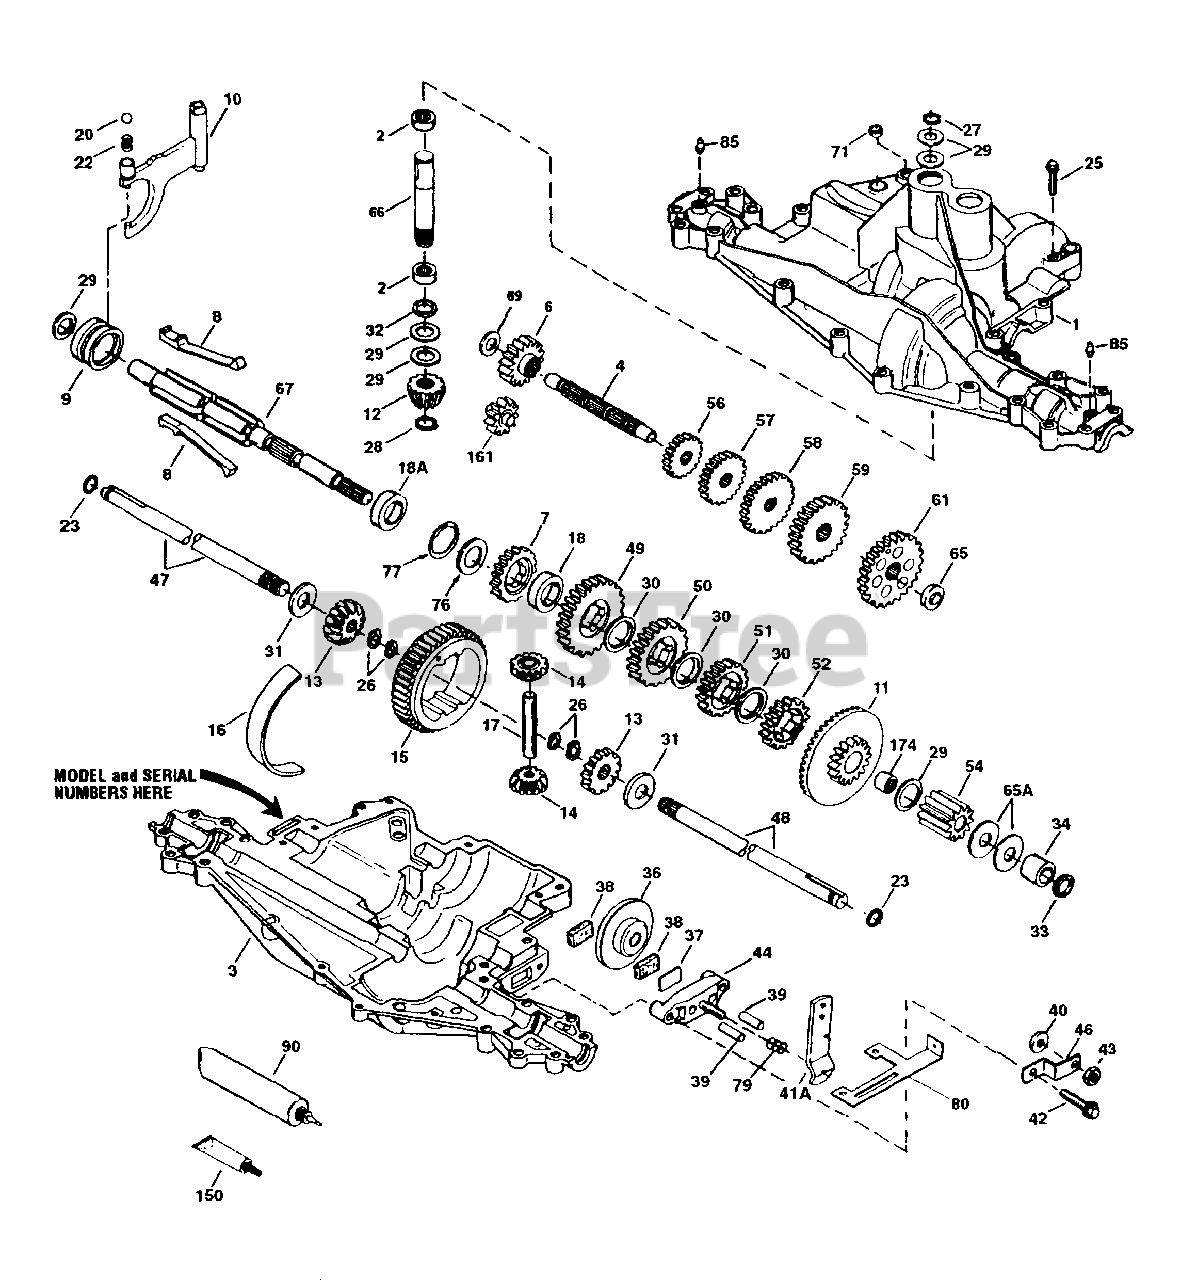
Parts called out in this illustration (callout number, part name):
1	Transaxle Cover
2	Needle Bearing
3	Transaxle Case
6	Spur Gear (16 teeth)
7	Spur Gear (22 teeth)
8	Shift Key
9	Shift Collar
10	Shift Rod 8 Fork
11	Bevel Gear & Bearing
12	Bevel Pinion (14 teeth)
13	Bevel Gear (16 teeth)
14	Differential Pinion
16	Bearing Strip
18	Neutral Spacer
18A	Neutral Spacer
20	Ball, 5/16" dia
25	Screw, 1/4-20 x 1-1/4"
26	Retaining Ring
27	Retaining Ring
28	Retaining Ring
37	Brake Pad Plate
38	Brake Pad (pkg. of 2)
40	Washer
42	Screw, 1/4-20 x 1-1/4"
43	Locknut, 5/16-24
44	Brake Pad Holder
46	Brake Lever Bracket
47	Axle (16-1/4" long)
48	Axle (11" long)
49	Spur Gear (30 teeth)
50	Spur Gear (25 teeth)
51	Spur Gear (22 teeth)
52	Spur Gear (19 teeth)
54	Spur Gear (11 teeth)
56	Spur Gear (20 teeth)
57	Spur Gear (25 teeth)
58	Spur Gear (28 teeth)
59	Spur Gear (30 teeth)
61	Spur Gear (34 teeth)
67	Shifter 8 Brake Shaft
71	Square Cut Ring
77	Inverted Retaining Ring (pkg. of 2)
80	Brake Bracket
85	Lubrication Fitting
90	Grease (32 oz. bottle Bentonite grease)
150	Gasket Eliminator (Loctite #515)
161	Reverse Idler
174	Needle Bearing
